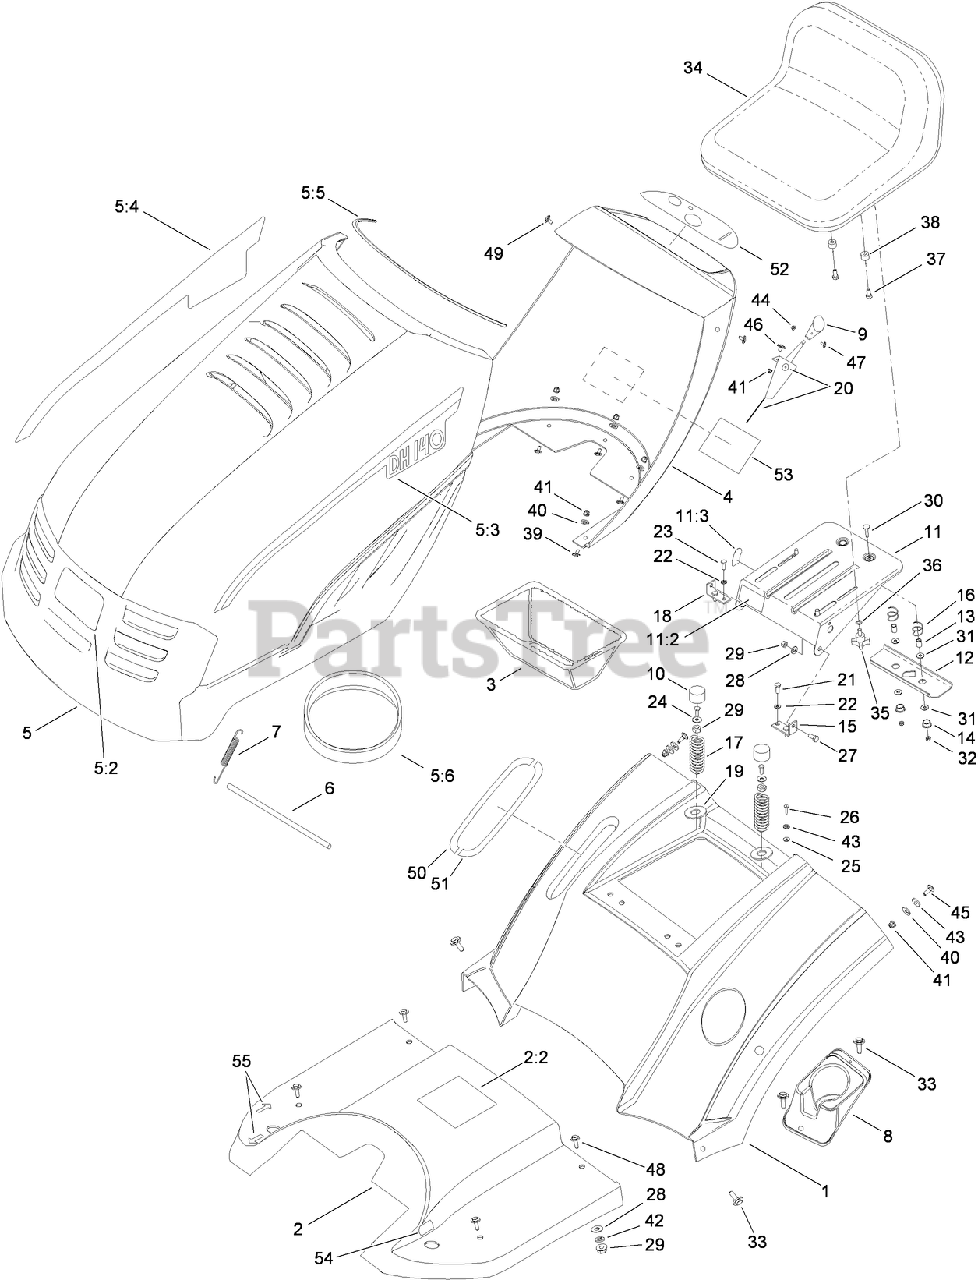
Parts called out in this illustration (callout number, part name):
1	FENDER-REAR
2	FOOT REST ASSEMBLY
2:2	DECAL-DANGER
3	BOX-BATTERY
4	PANEL-DASH
5	HOOD ASM
5:3	DECAL-DH 140 (LH)
5:4	DECAL-DH 140 (RH)
5:5	RUBBER-PURL
5:6	GASKET-FOAM
6	BAR-SAFETY
7	SPRING-HOOD
8	BOX-DRINK
9	KNOB-THROTTLE/CHOKE
10	CAP-HUB
11	BRACKET-SUPPORT, SEAT
11:2	DECAL-DANGER
11:3	DECAL-SWITCH
12	BRACKET
13	SPACER-SPLIT
14	BUSHING
15	HOLDER-SUPPORT, LEFT
16	SEAT-SPRING
17	SPRING-SEAT
18	HOLDER-SUPPORT, RIGHT
19	WASHER-SEAT SPRING
20	CABLE-THROTTLE/CHOKE
21	SCREW-HH
22	WASHER-SPRING
23	SCREW-HH
24	WASHER-PLAIN
27	SCREW-SUPPORT, SEAT
28	WASHER-PLAIN
29	NUT-LOCK, NI
30	SCREW-CARR
31	WASHER-FLAT
32	NUT-LOCK
35	KNOB-ADJUST
36	WASHER-SPRING
37	SCREW-HHF
38	SPACER
39	SCREW-HEX
40	WASHER-FLAT
41	NUT-LOCK
42	WASHER-RUBBER
43	WASHER-RUBBER
44	NUT-HEX
46	SCREW-FLAT HEAD
50	DECAL-MOWING LIFT, RIGHT
51	DECAL-MOWING LIFT, LEFT
52	DECAL-PANEL
54	DECAL-BRAKE, PARKING
55	DECAL-TRAVEL
